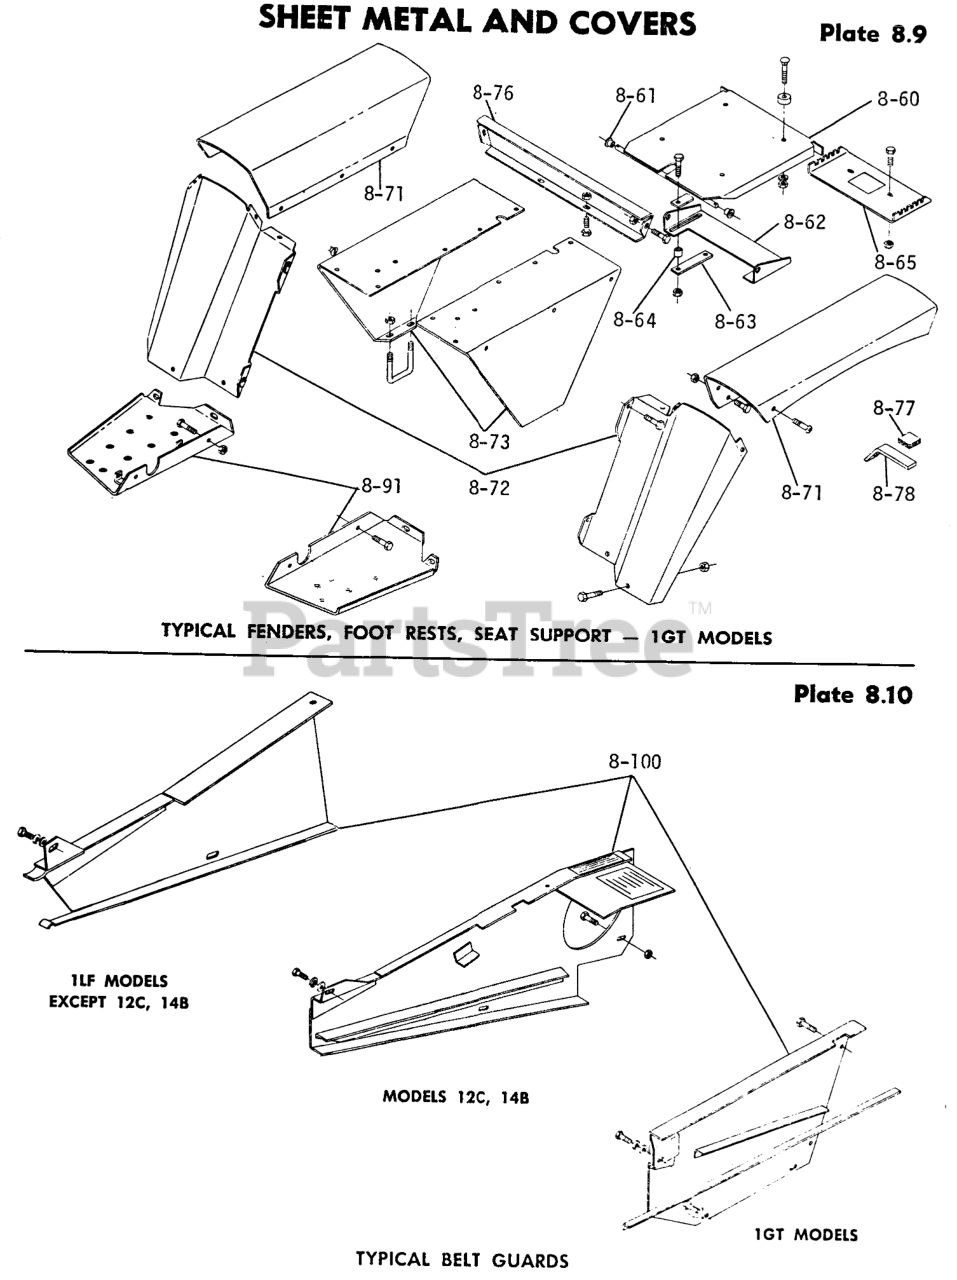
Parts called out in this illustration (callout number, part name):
8-100	Assy.-Belt Guard
8-100	Bolt 3/8-16 x 3/4
8-100	Lockwasher
8-100	Washer
8-100	Bolt 5/16-18 x
8-100	Nut 5/16-18
8-100	Bolt, 5/16-18 x 1/2
8-100	Bolt Hex 7/16-4 x 3/4
8-100	Lockwasher 3/8
8-100	Washer 7/16
